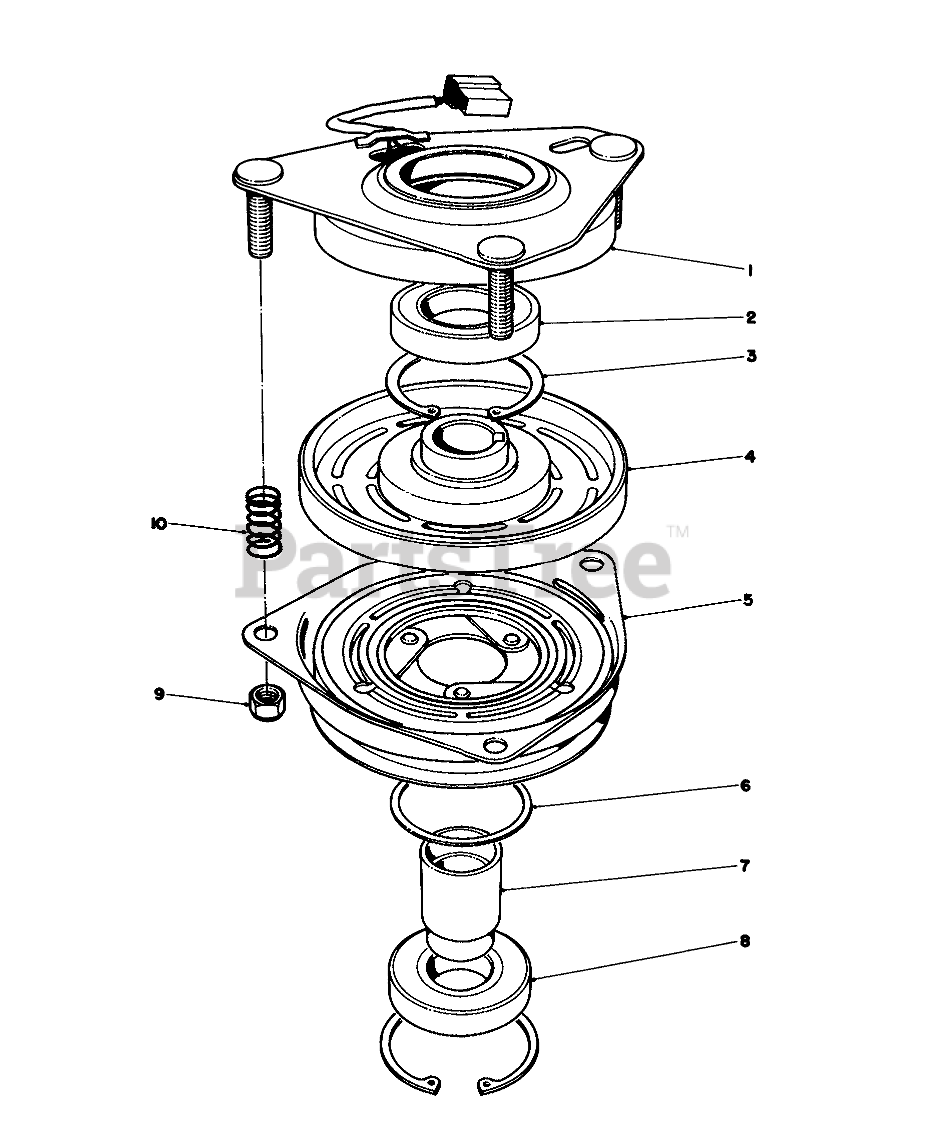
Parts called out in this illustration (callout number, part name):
1	Field Assembly (Incl. Ref #2 & 3)
2	BEARING-FIELD
3	RING-RETAINING
4	Field Coil, Rotor & Bearing Assembly (Incl. Ref. #1)
5	Armature & Pulley Assembly (Incl. Ref. #3, 6, 7 & 8)
6	SPACER-BEARING, PULLEY
7	COLLAR-BEARING
8	BEARING-PULLEY
9	NUT-LOCK
10	SPRING
